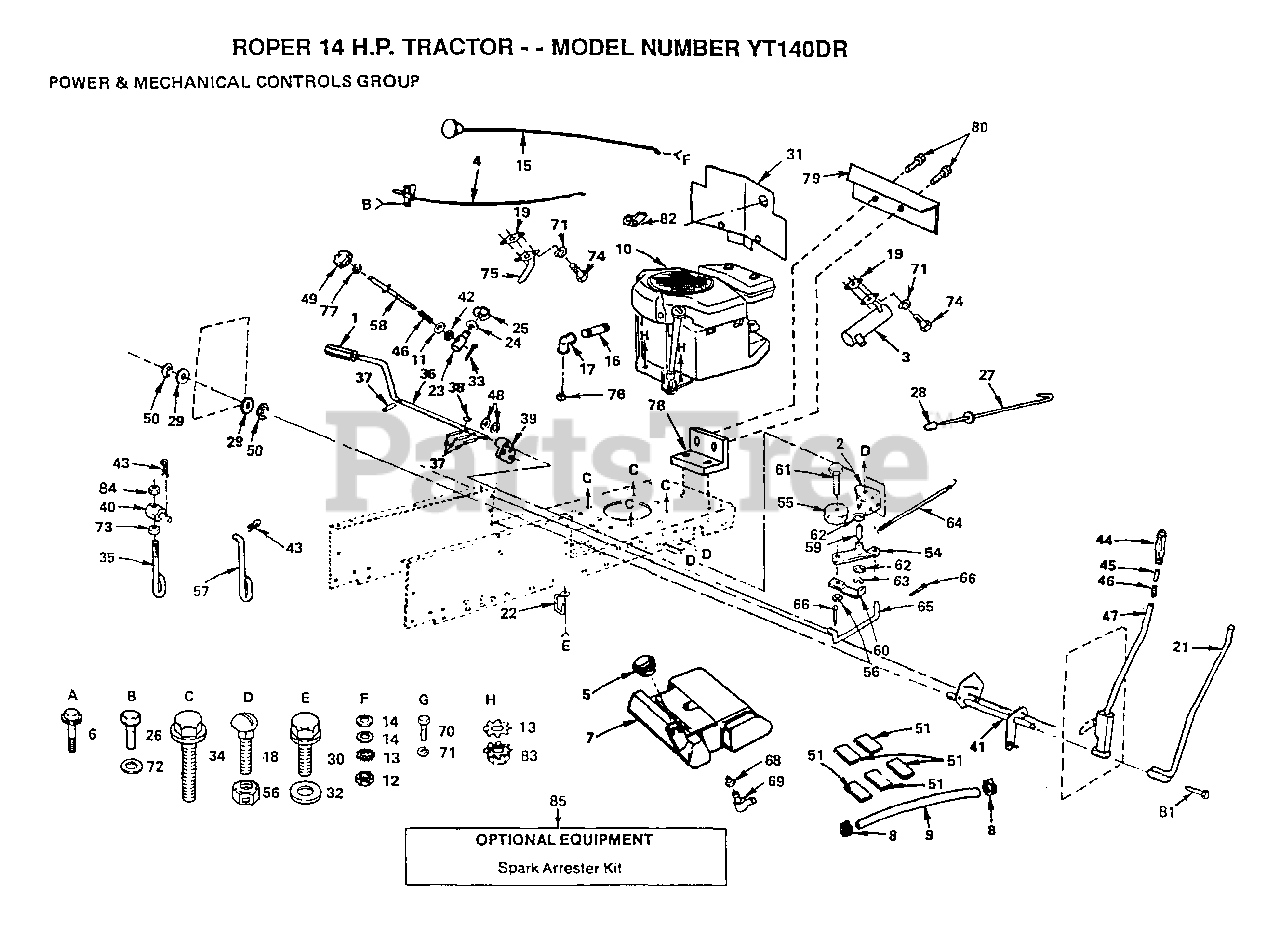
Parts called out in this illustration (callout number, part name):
1	PEDAL COVER T
11	WASHER
13	LOCKWASHER
14	WASHER
16	PIPE NIPPLE LT
17	ELBOW
18	BOLT
21	LEVER ROD LT
23	TRUNION LT
24	WASHER
25	KLIP RING
26	SCREW
28	PLUNGER CAP T
29	WASHER
30	SCREW
32	WASHER
34	SCREW LT
35	PIVOT PIN T
36	FOOT SHAFT PEDAL
39	ARM BRAKE LT
41	SHAFT LIFT LT
42	NUT T
44	GRIP
46	SPRING T
48	WASHER
49	HDLE ADJ LIFT
50	E-RING
51	PAD-SPACER T
54	"ASS T, BELLCRAN"
57	LIFT LINK LT
58	ROD LIFT LT
59	"LY, BEARING"
62	WASHER LT
63	KLIP RING
64	"SPRING, RETURN LT"
65	"LINK, CLUTCH T"
66	COTTER PIN
68	BUSHING OUTLET T
69	FUEL TANK STEM GT
70	BOLT
71	LOCKWASHER
73	NUT
75	EXHAUST TUBE T
76	PLUG OIL DRAIN
77	NUT
78	BRACKET HEAT SHIELD
79	BAFFLE - VERTICAL
80	SCREW LT
81	"BOLT,HEX"
82	INSUL CLIP T
83	NUT
